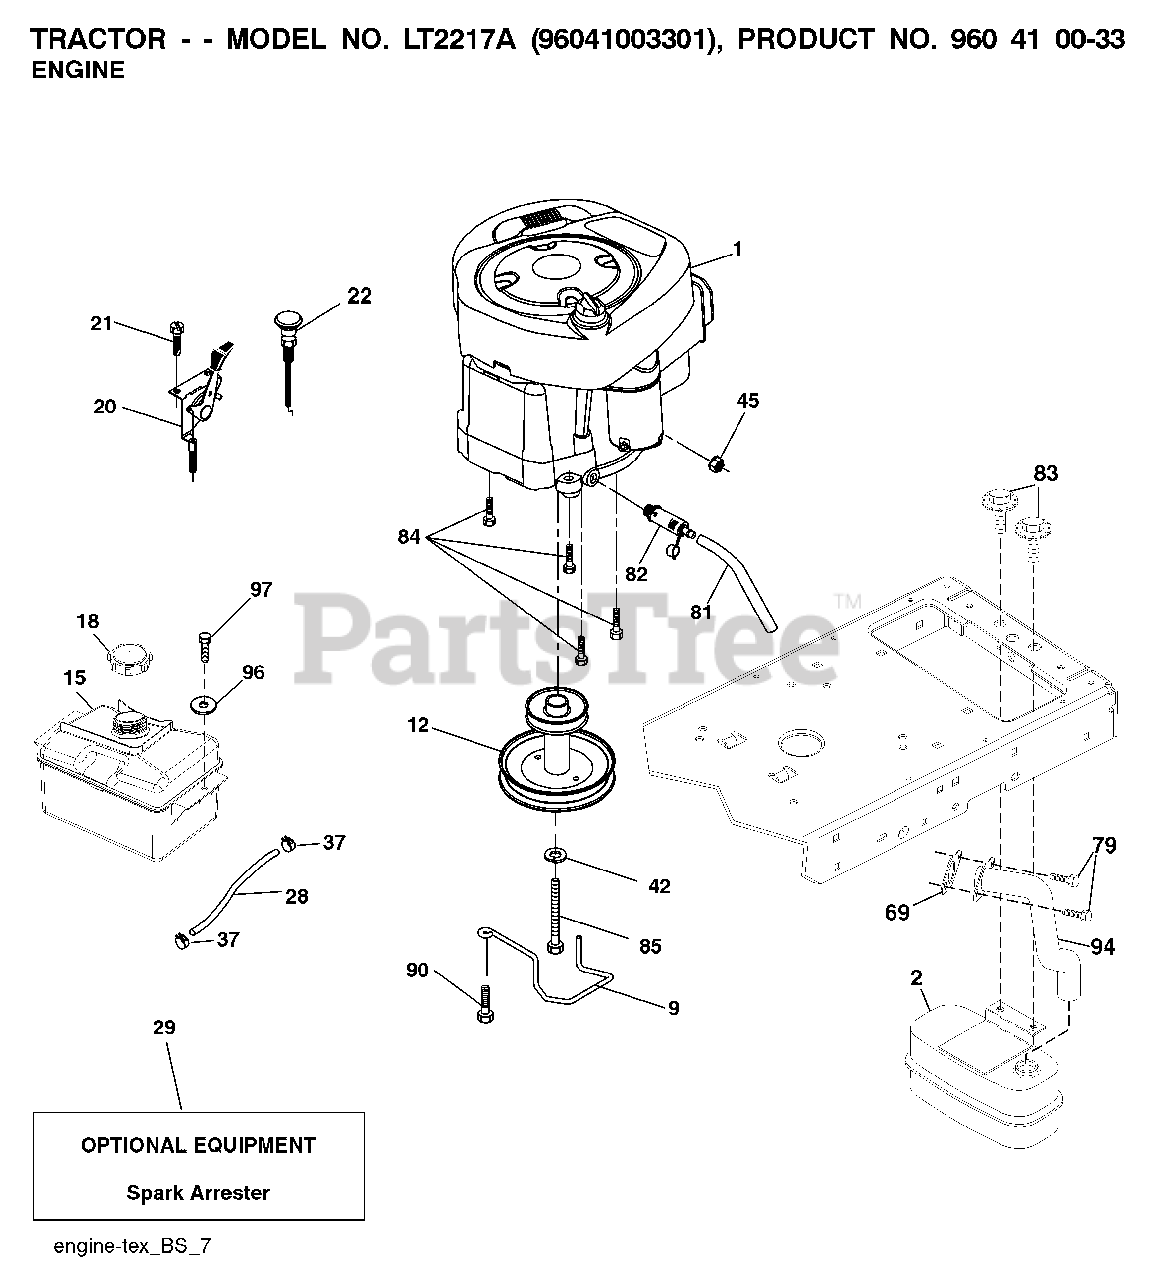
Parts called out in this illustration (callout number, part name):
2	MUFFLER.SINGLE.CYL.KOHL/B&S
9	KEEPER.BELT.ENGINE.3.25
12	PULLEY ENGINE
15	TANK FUEL FRT 1.5 GAL
18	FUEL CAP
20	CONTROL.TH/CK.C.
21	SCREW
28	LINE.FUEL.20
29	ARRESTER SPARK (OPTIONAL)
37	HOSE CLAMP
42	LOCKWASHER
45	NUT
69	REPL BY 532 27 22-93
79	SCREW.SOCKET HD.5/16-1
81	TUBE, DRAIN OIL ASM.
82	PLUG DRAIN OIL EASY
83	BOLT, 5/16-18 X 1 3/4
84	SCREW.3/8-16
85	BOLT HEX 7/16-20X4-1/4"
90	SCREW 3/8-16X1
94	EXHAUST.TUBE.B&S.
97	SCREW HEXWSHR 1/4-20X3/4
102	SCREW
107	SCREW.1/4-20X5/8
